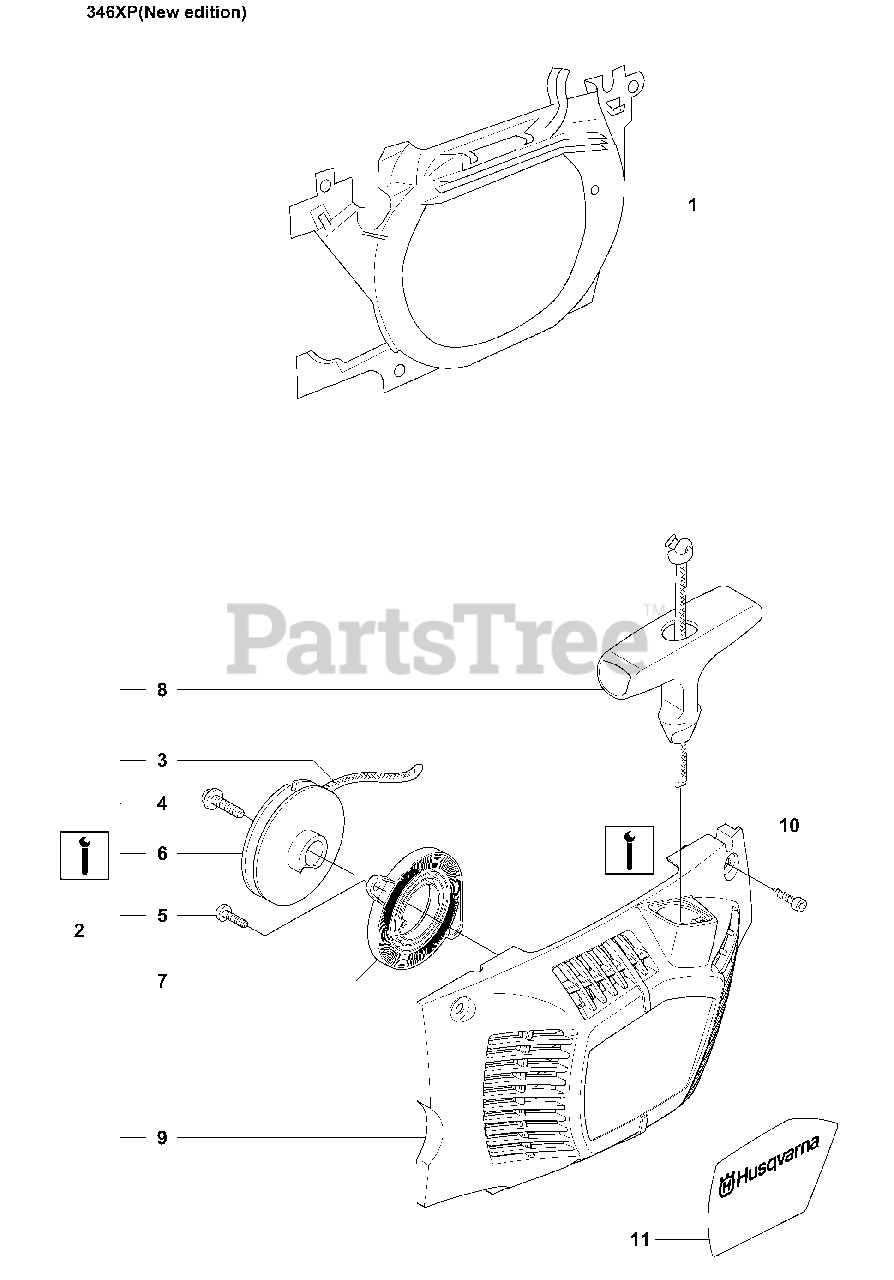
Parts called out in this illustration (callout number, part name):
1	AIR CONDUCTOR
3	STARTER ROPE
6	PULLEY
7	RETURN SPRING
8	STARTER HANDLE
9	STARTER HOUSING
11	LABEL
11	Label
